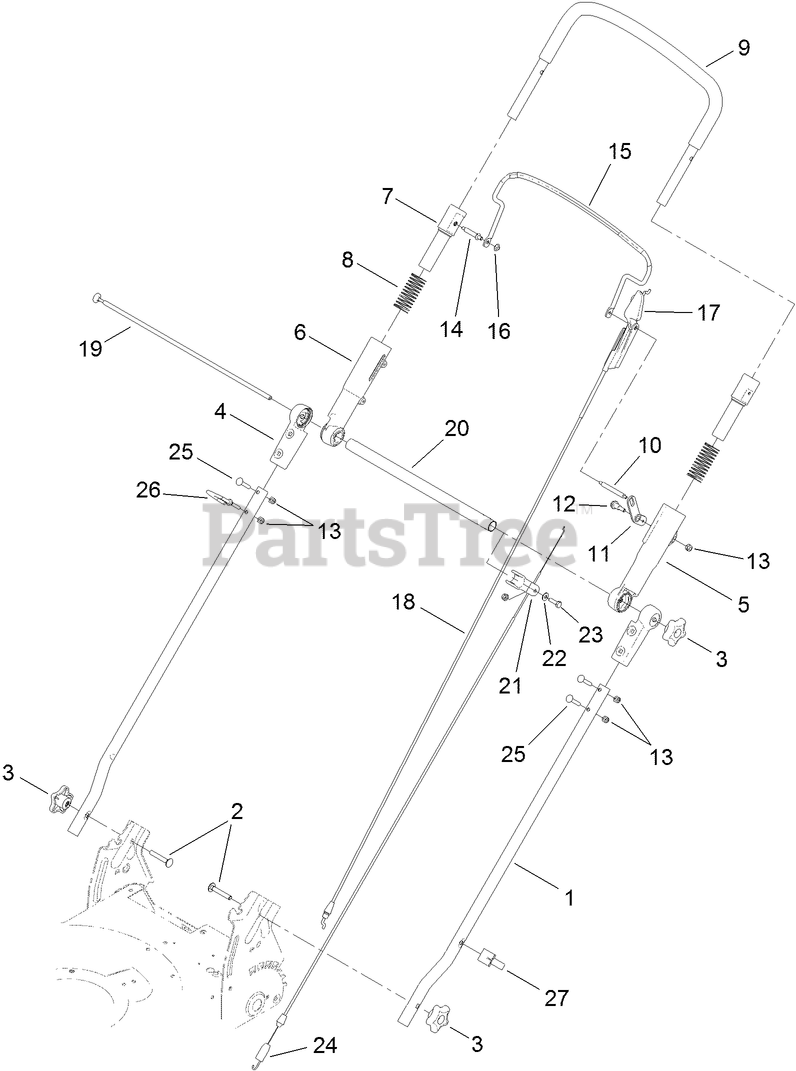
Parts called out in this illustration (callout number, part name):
1	HANDLE-LOWER
2	BOLT-CARR
3	KNOB-HANDLE
4	MOUNT-HANDLE, LOWER
5	SLEEVE-OUTER, LH
6	SLEEVE-OUTER, RH
7	SLEEVE-INNER
8	SPRING-COMPRESSION
9	UPPER HANDLE ASM
10	PIN-BAIL, LH
11	LEVER-TRACTION
12	BOLT-SHOULDER
13	NUT-LOCK, NI
14	PIN-HANDLE
16	RETAINER-PUSH ON
17	STOP-PIVOT
18	CABLE-BRAKE
19	ROD-THREADED
21	CLAMP-CABLE
22	WASHER-FLAT
23	SCREW-HH
24	CABLE-TRACTION
25	SCREW-CARR
26	GUIDE-ROPE, UPPER
27	GUIDE-CABLE
